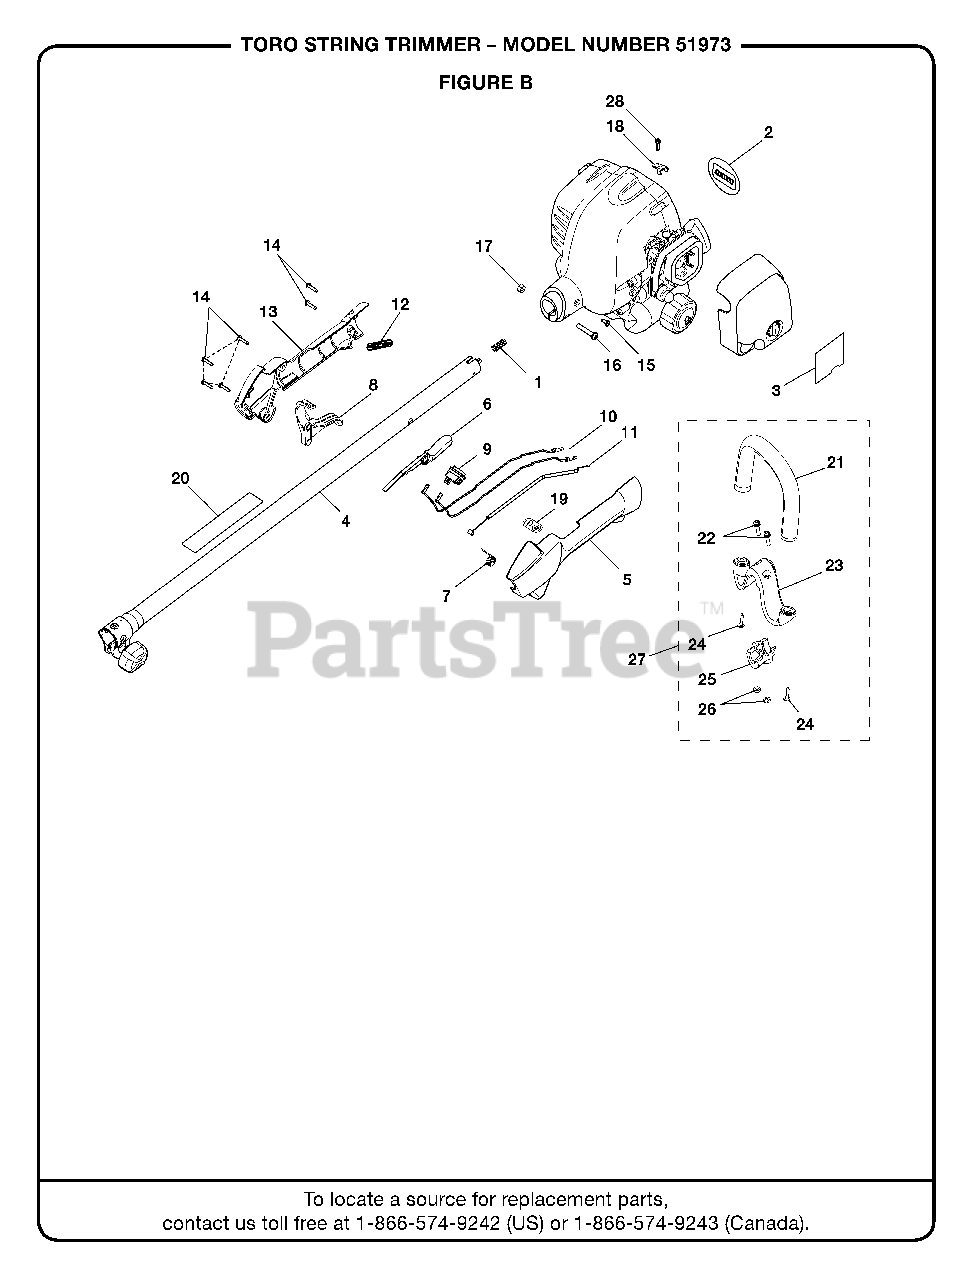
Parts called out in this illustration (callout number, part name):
1	COMPRESSION SPRING
2	LOGO PLATE
3	LOWER START LABEL
4	UPPER SHAFT ASSEMBLY
5	REAR HANDLE SUPPORT
6	LOCK-OFF BUTTON
7	TRIGGER SPRING
8	TRIGGER
9	SWITCH WITH DUST SHIELD
10	LEAD
11	CABLE, THROTTLE
12	CORRUGATED TUBE
13	REAR HANDLE COVER
14	SCREW (M4 X 16 mm)
15	SCREW (#8-16 X 1/2 in. TRI-LOBULAR)
16	SCREW (M6 X 1-30 mm)
18	THROTTLE CABLE CLAMP
19	ON/OFF LABEL
20	WARNING LABEL
21	ASSIST HANDLE W/GRIP
22	SCREW (#12-24 X 1 in.)
24	SLOTTED TORX SCREW
25	CLAMP
26	HEX NUT (12-24)
27	ASSIST HANDLE ASSEMBLY
28	SCREW (M4 X 16 mm)
